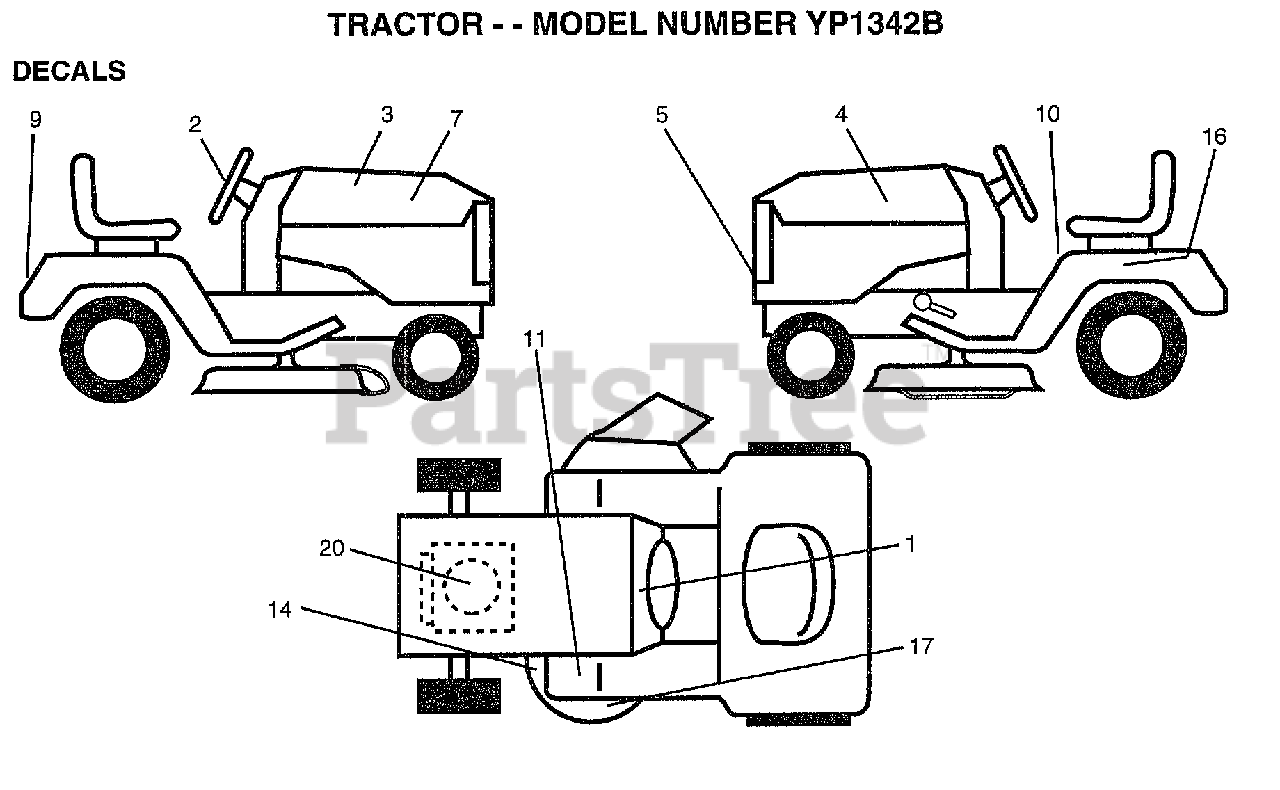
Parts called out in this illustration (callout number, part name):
1	"DECAL DASH,OPER."
2	"DECAL INSERT,STRG"
3	DECAL.HOOD.RH
4	DECAL HOOD LH
9	DECAL FENDER
10	"DECAL DANGER,FEND"
14	"DECAL-SCHEM,BELT"
16	DECAL.BATRY.3-3908
17	DECAL CHASSIS
20	DECAL HP ENGINE
